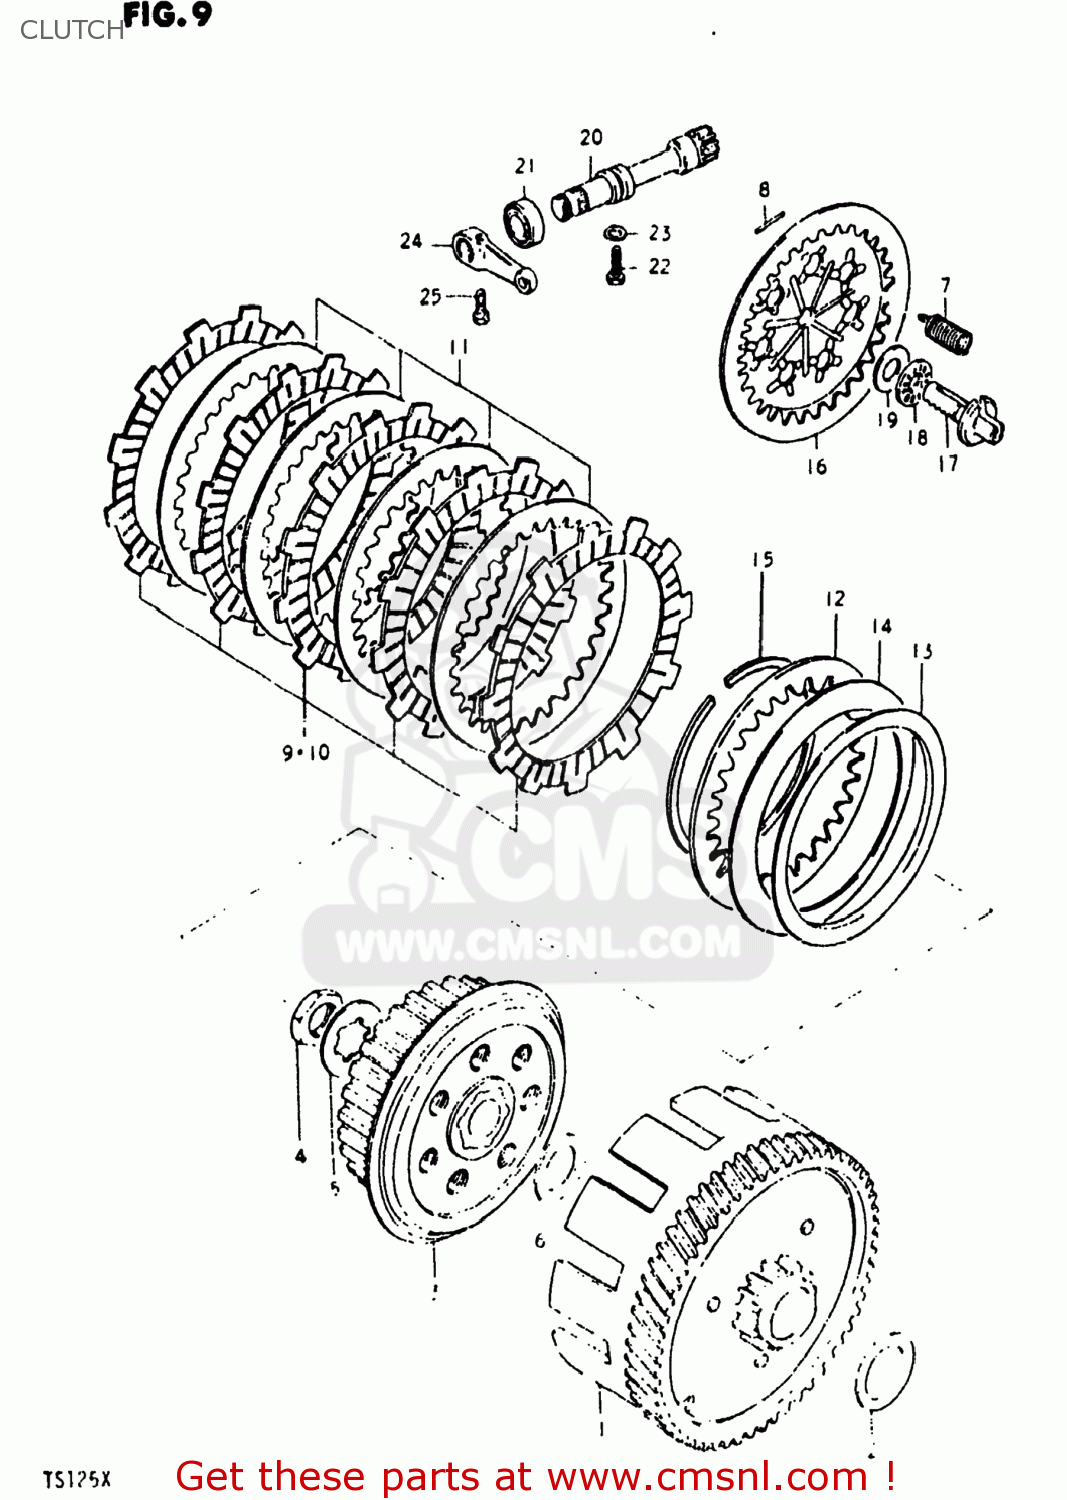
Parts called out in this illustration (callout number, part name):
1	GEAR ASSEMBLY,PRIMARY DRIVE
2	WASHER
3	HUB,CLUTCH SLEEVE
4	NUT
5	WASHER,LOCK
6	WASHER
7	SPRING
8	PIN(2.5X19.8)
9	PLATE,CLUTCH DRIVE
10	PLATE,CLUTCH DRIVE (MCA)
11	PLATE,CLUTCH DRIVEN (NAS)
12	PLATE,CLUTCH DRIVEN(T:2.0) (NAS)
13	SEAT,WAVE WASHER
14	WASHER
15	CIRCLIP
16	PLATE,CLUTCH PRESSURE
17	BACK,CLUTCH RELEASE
18	BEARING(10X22X2.8)
19	WASHER(10.1X21.4X0.8)
20	PINION,CLUTCH RELEASE
21	OIL SEAL
22	BOLT(6X12)
23	WASHER
24	ARM,CLUTCH RELEASE
25	BOLT
